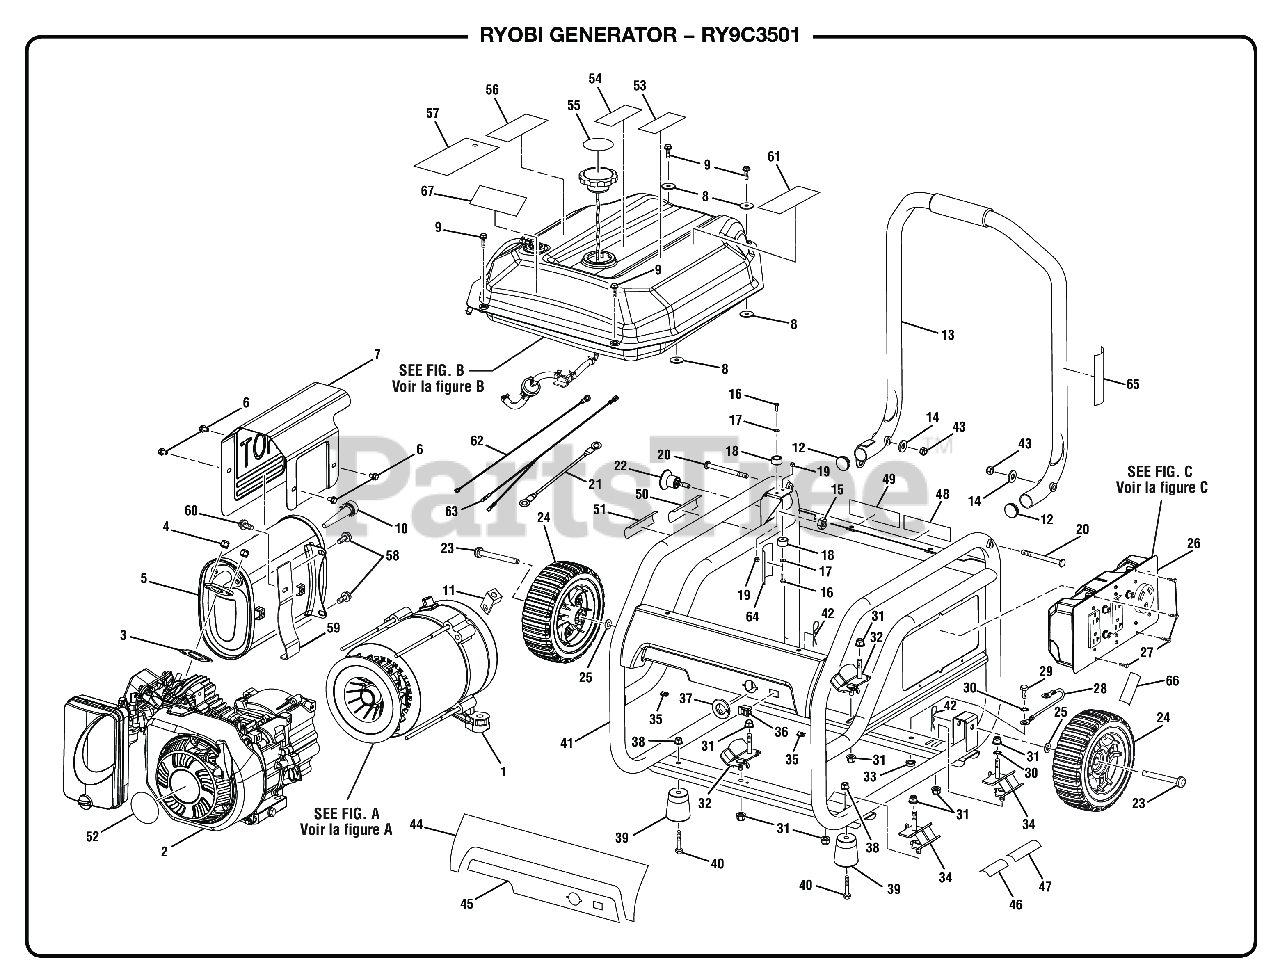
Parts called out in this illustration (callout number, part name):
1	Generator Head Assembly
2	Engine (RATO R210)
3	Muffler Gasket
4	Lock Nut (M8)
6	Bolt (M6 x 10 mm, Hex Flange Hd.)
7	Heat Shield
8	Washer (1/4 in., Type A)
9	Bolf (M6 x 20 mm, Hex Washer Hd.)
10	Spark Arrestor
11	Ground Lug
13	Handle Assembly
14	Washer ( 5/16 in.)
15	Lock Nut (1/2-20, Hex)
16	Hex Screw (M4 x 12 mm, Hex Button Hd.)
17	Washer (M4)
18	Rubber Bumper
19	Flange Nut (M4 x 0.7 in.)
20	Handle Pivot Pin (5/6-18 x 90 mm)
21	Bonding Wire
22	Handle Lock Assembly
23	Axle Bolt
25	Washer (OD19.75 x ID10.5 x 1t)
26	Control Panel Assembly
27	Screw (6-20 x 3/8 in., Phillips Pan Hd.)
28	Assembly, ground wire
29	Bolt (5/16-18 x 3/4 in., Hex. Hd.)
30	Washer (5/16 in., External Star)
31	Lock Nut (M8 x 1.25 mm, Flange)
32	Isolator (Left)
33	Flange Nut (5/16-18, Hex Hd.)
34	Isolator (Right)
35	U-Clip (M6)
36	Switch (Momentary Contact)
37	Fuel Valve Bezel
38	Lock Nut (M8 x 1.25)
39	Foot Assembly
40	Bolt (M8 x 1.25 in., Flange Hex Hd.)
41	Carrier Assembly
42	Hitch Pin (M3)
43	Lock Nut (5/16-18, Hex Hd.)
44	Performance Label
45	Start Label
46	Inquires Label (Ryobi)
47	Engine Lubricant Label
48	Ground Warning Label
49	Fire Distance Label (Eng/Sp)
50	Hot Surface and Exhaust Label
51	UL Fire Warning Label Spark Arrestor)
52	Recoil Label
53	CPSC (English) Label
54	No E85 Label
55	Remove Cap Fuel Stabilizer Label (English)
56	Danger Label
57	Warning Hangtag
58	Bolt (M8 x 1.25 in., Flange Hex Hd.)
59	Muffler Bracket
60	Bolt (M6 x 14 mm, Flange Hex Hd.)
61	Risk of fire danger label
62	Off Switch Wire Assembly (Black)
63	Wire Assembly Wire (Green)
64	Handle Release Label (Eng/Sp)
65	Remove Cap Fuel Stabilizer Label (Spanish)
66	Logo Label (Small)
67	Logo Label (Large)
